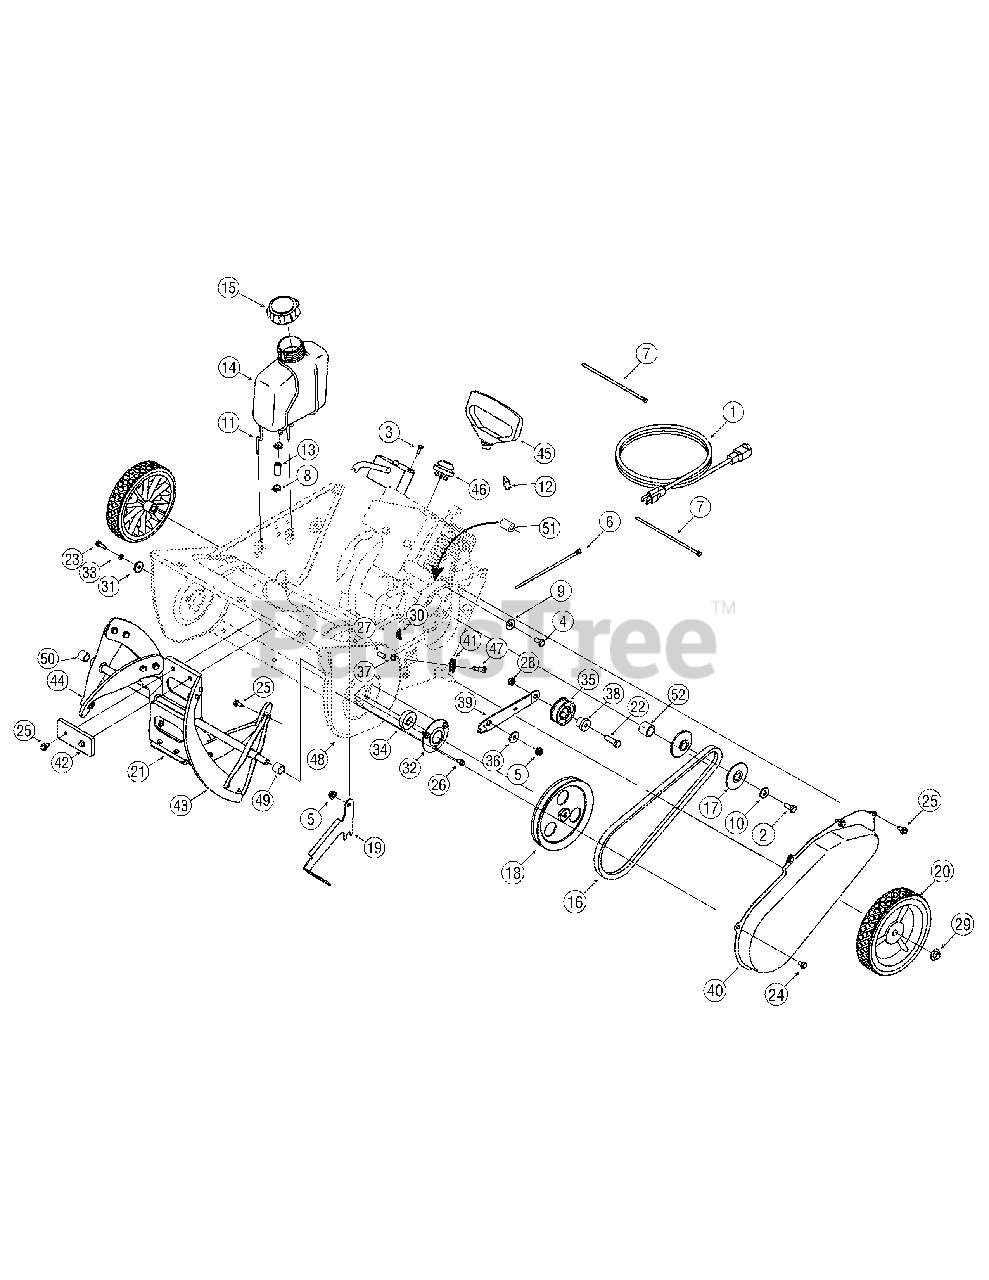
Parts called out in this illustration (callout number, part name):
1	Cord-Extension 110V3M 2 Prong
2	Hex L-Bolt 5/16-24 x .75 Gr. 5
3	Hex Wash B-Tapp Scr #10 x .62" Lg.
4	Screw-Hex Cap 5/16-18 x 1.5 Gr. 5
4	Screw-Hex Cap 5/16-18 x .625 Gr. 5
5	Flange Locknut 5/16-18 Gr. F, Nylon
6	Cable Tie
7	Push Mount Tie
8	Hose Clamp
9	Lockwasher 5/16
10	Cupped Washer .340 ID x .872 OD x .06
11	Gas Tank Support Wire
12	Choke Lever Knob
13	Fuel Line
14	Fuel Tank 2 Quart
15	Cap-Fuel
16	V-Belt
16	V-Belt 1/2 x 35.0" Lg.
17	Pulley Half .625 ID x 2.25 OD
18	Pulley
18	V-Pulley 1/2 x 6,0" OD
22	Hex Screw 1/4-20 x 1.25 Gr. 5
23	Thd Forming Scr. 1/4-20 x .75 Lg.
24	Hex Wash HD Tapp Scr 1/4-20 x .375
25	Hex B-Tap Scr 1/4-28 x .25" Lg
26	Hex Tap Scr. 1/4-14 x .5" Lg.
27	Hex Bolt 5/16-18 x .75" Lg. Gr. 5
28	Flange Locknut 1/4-20 Gr. F, Nylon
29	Push Cap x 1/2" Rod
30	Extension Spring .33 OD x 1.12 Lg.
31	Flat Washer .25 ID x .93 OD x .125
33	L-Wash 1/4 ID
34	Ball Bearing .625 x 37 x 12.63
35	Idler Pulley (1/4" hole)
36	Shoulder Spacer .25 Thk.
37	Hex Ins Jam L-Nut 1/4-28
38	Shoulder Spacer
41	Cable Guide Roller
42	Rubber Paddle
43	Rubber Spiral-Crescent
45	Recoil Handle,Mitten
46	Primer
47	Hex Shld.Scr.1/4-28 x .375
49	Auger Spacer LH
50	Auger Spacer RH
51	Spacer .325 ID x .625 OD x .88
52	Spacer .630 x .88 x .747
